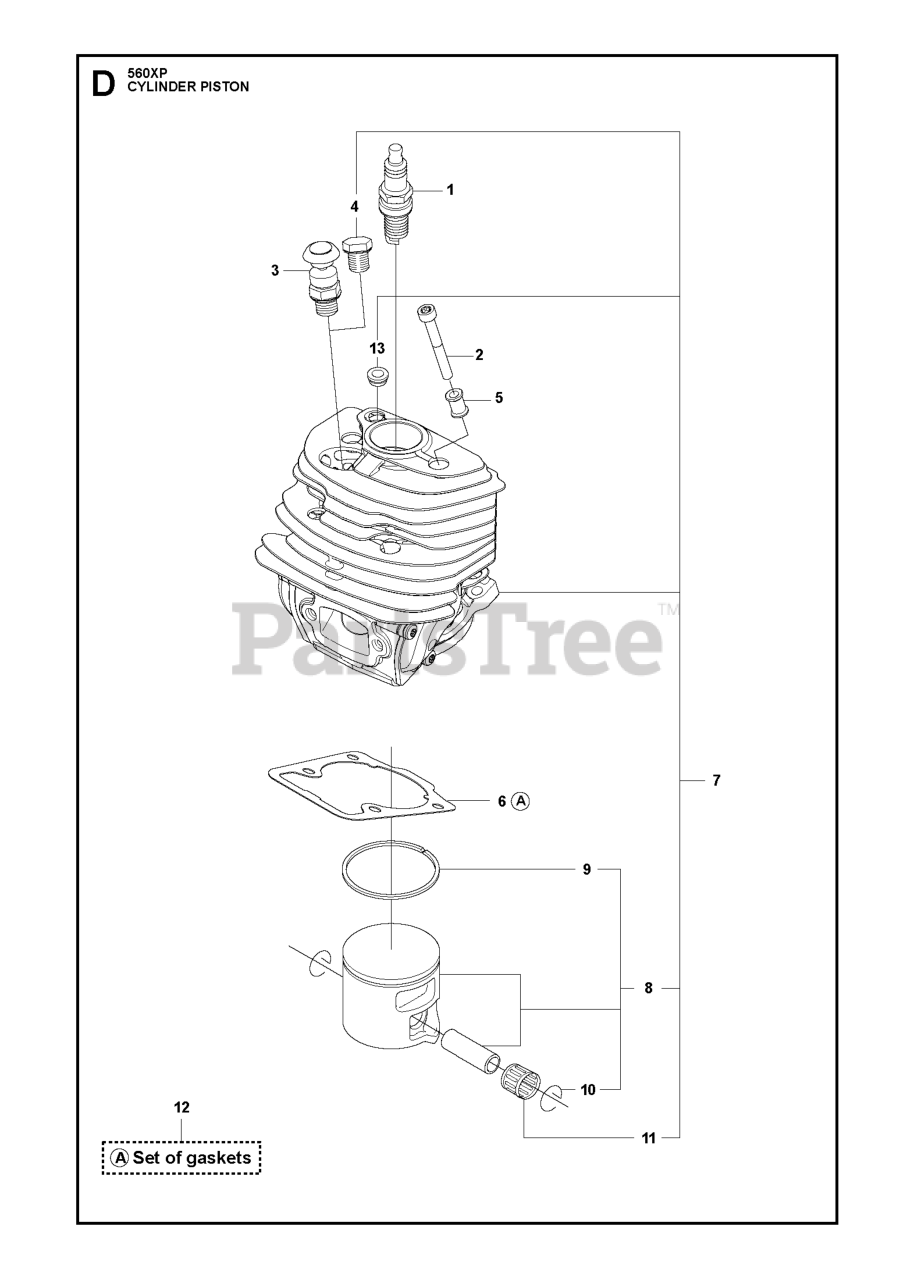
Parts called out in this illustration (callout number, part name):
1	CMR6H SPARK PLUG NGK
2	SCREW HEXABOULAR SOCKET HEAD C
3	DECOMPRESSION VALVE
4	CYLINDER PLUG
7	CYLINDER ASSY
8	PISTON ASSY
9	PISTON RING
10	LOCKING RING
11	SUPPORT BUSHING
12	GASKET KIT
